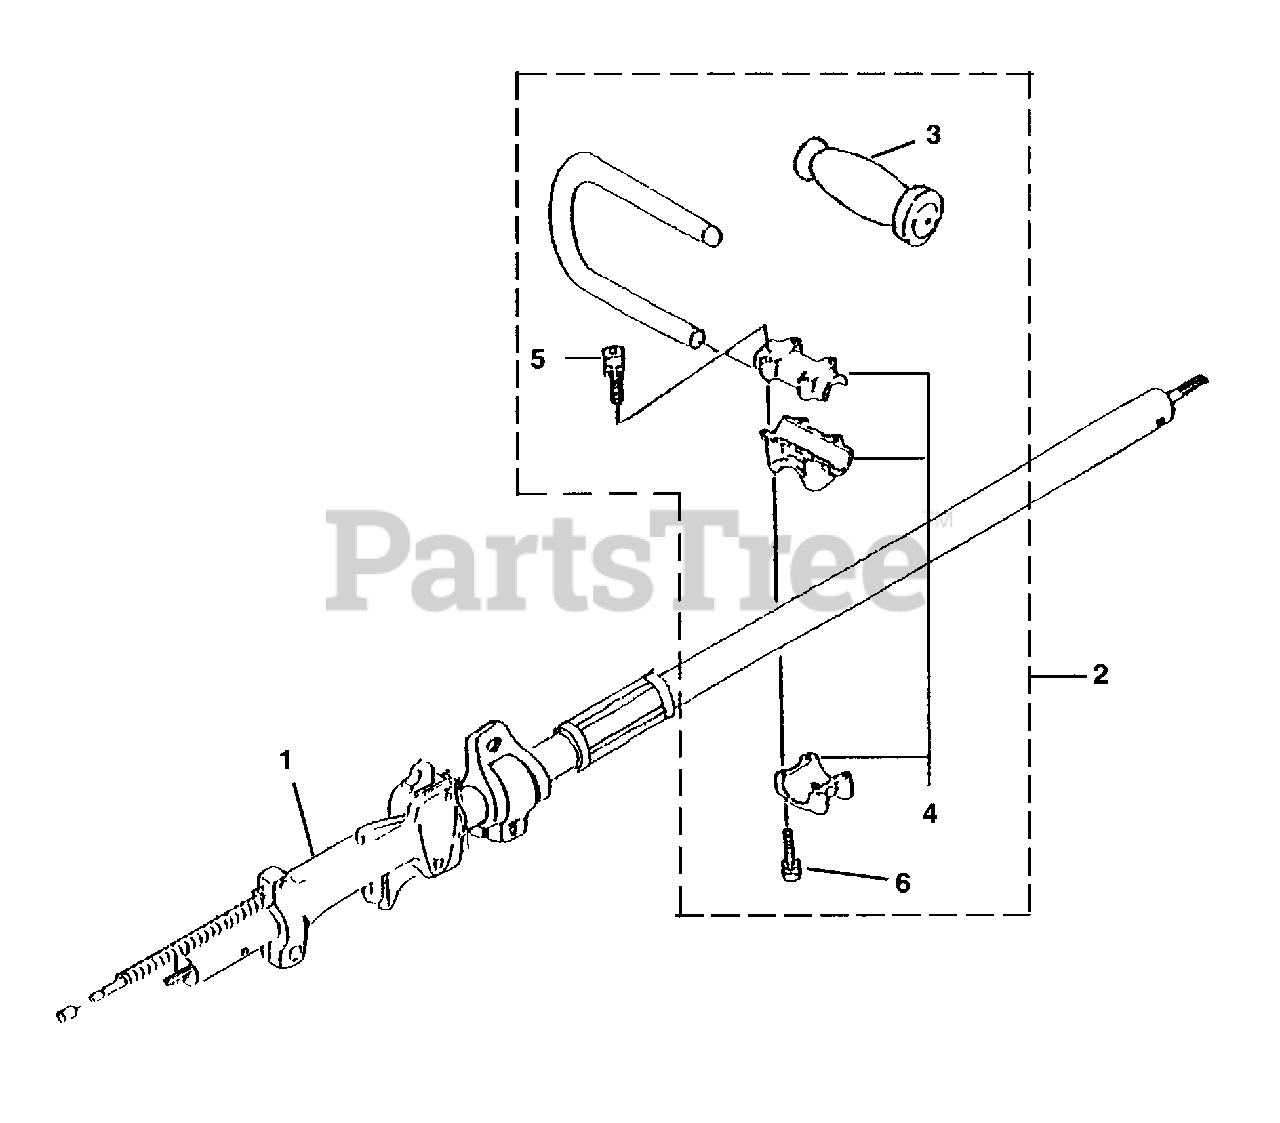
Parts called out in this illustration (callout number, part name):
1	CONTROL LEVER ASSEMBLY
2	HANDLE ASSEMBLY
4	HANDLE-Bracket Assembly
5	BOLT-Socket Hd (M5 x 25 SW)
6	BOLT-Socket Hd (M5 x 25 SW)
